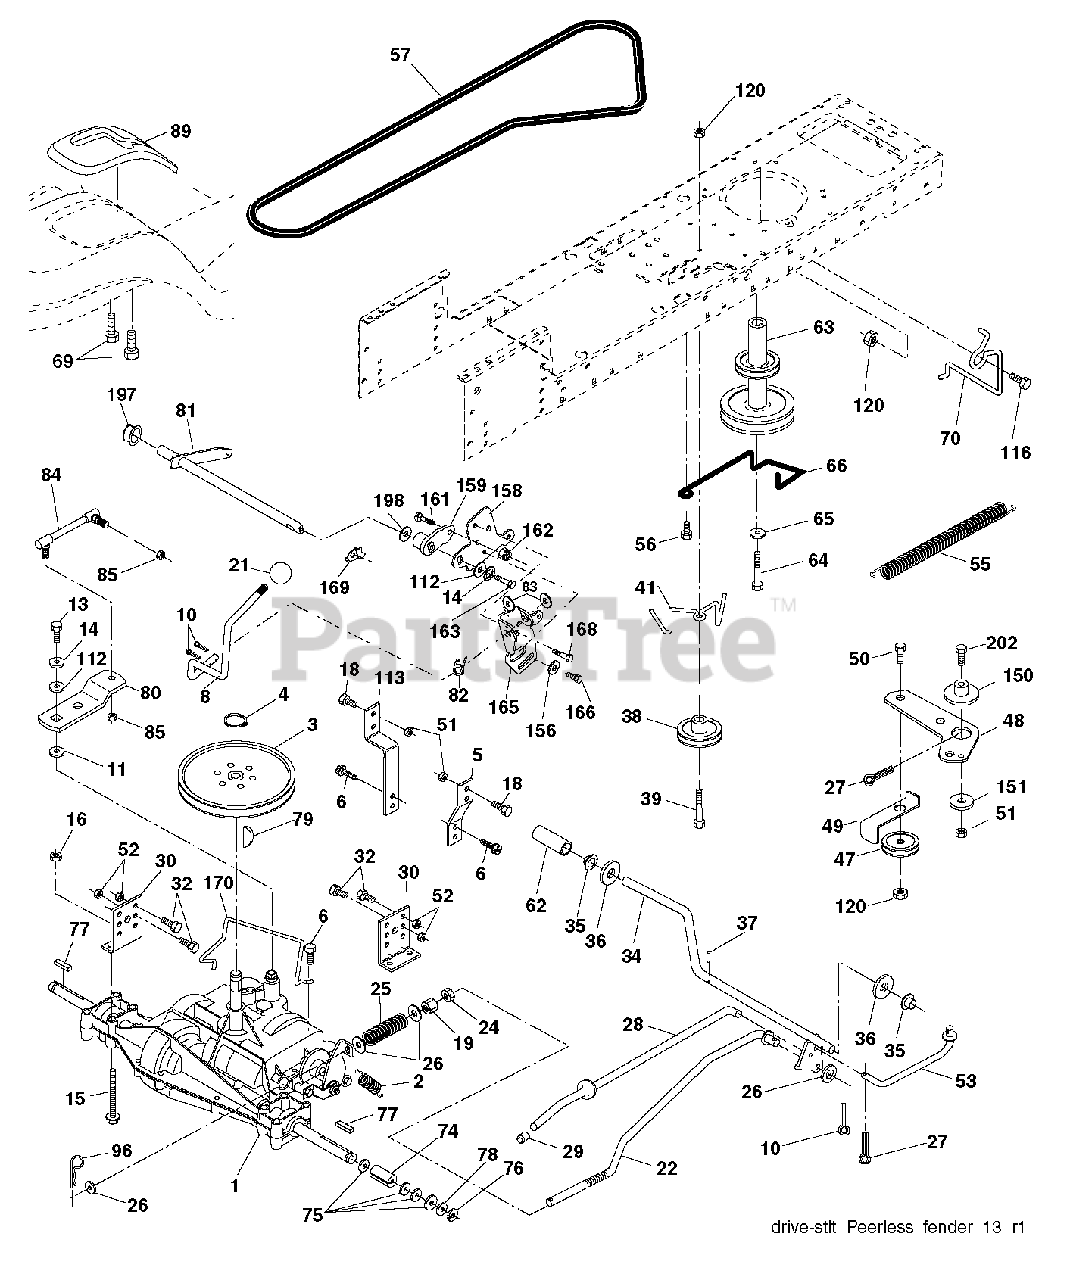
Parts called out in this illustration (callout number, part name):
1	TRANSAXLE(206-545C)PMST 6 LTST
2	SPRING,BRAKE RETURN
3	PULLEY TRANS
4	RETAINING RING LT
5	STRAP TORQUE
6	SCREW 5/16"
8	ROD SHIFT FENDER ADJUST LT
10	PIN COTTER
11	WASH-SHFT PLT LT
13	Bolt, 1/4-20 unf Grade 8 w/Patch
14	LOCKWASHER
16	NUT.71038.31-18.HEX.NYLOCK
19	NUT
21	KNOB T (1/2-HOLE)
22	ROD BRAKE
24	NUT
25	SPRING ROD LT
27	COTTER PIN
28	ROD, PARKING BRAKE
29	PLUNGER CAP
30	BRKT, TRNSXLE MNT 20"
32	BOLT
34	SHAFT, FOOT PEDAL
35	BEARING.NYLON
36	WASHER LT
37	Drive Pin, 3/16 X 1"
38	PULLEY IDLER COMPOSITE
41	KEEPER, BELT IDLER
47	Idler Pulley
48	BELLCRANK, CLUTCH
49	RETAIN BELT
50	BOLT.3/8-16X1.50
51	LOCKNUT
52	LOCKNUT
53	LINK.CLUTCH.7.66.2005
55	SPRING, RETURN LT
56	SCREW.3/8-16
57	BELT, V GROUND DRIVE 95 25
63	ENGINE PULLEY
64	BOLT HEX 7/16-20X4-1/4"
65	LOCKWASHER
66	KEEPER BELT ENGINE
69	SCREW.HI-LO.CONSOLE
70	KEEPER BELT ENG
74	SPACER AXLE
76	E-RING LT
77	SQUARE KEY
79	KEY STD (1373) DANA
80	ARM SHIFT
81	SHAFT ASM CROSS TAPERED PMST/2
82	SHIFT SPRING
83	WASHER
84	LINK.TRANSAXLE.PMST/DANA.20"
85	NUT LOCK CENTER 1/4 -28 FNTHD
89	CONSOLE SHIFT STLT
112	WASHER LT
113	STRAP TORQUE LH LT
120	NUT LOCK FLG 3/8-16 UNC
150	SPACER, RETAINER
151	WASHER 12/32X2X10GA
156	WASHER.SRRTD.5/16
158	BRACKET.SHIFT.MOUNT
159	HUB.SHIFT
161	BOLT
162	NUT.CROWNLOCK.1/4
165	BRACKET.PIVOT.LEVER
168	BOLT.SHOULDER.5/16-18X
169	PLATE.FASTENING.CROSS.SHAFT
170	KEEPER BELT T/A
197	NYLINER SNAP 5/8" ID
198	WASHER.NYL.7/8IDX.105"HYD CR
202	BOLT
